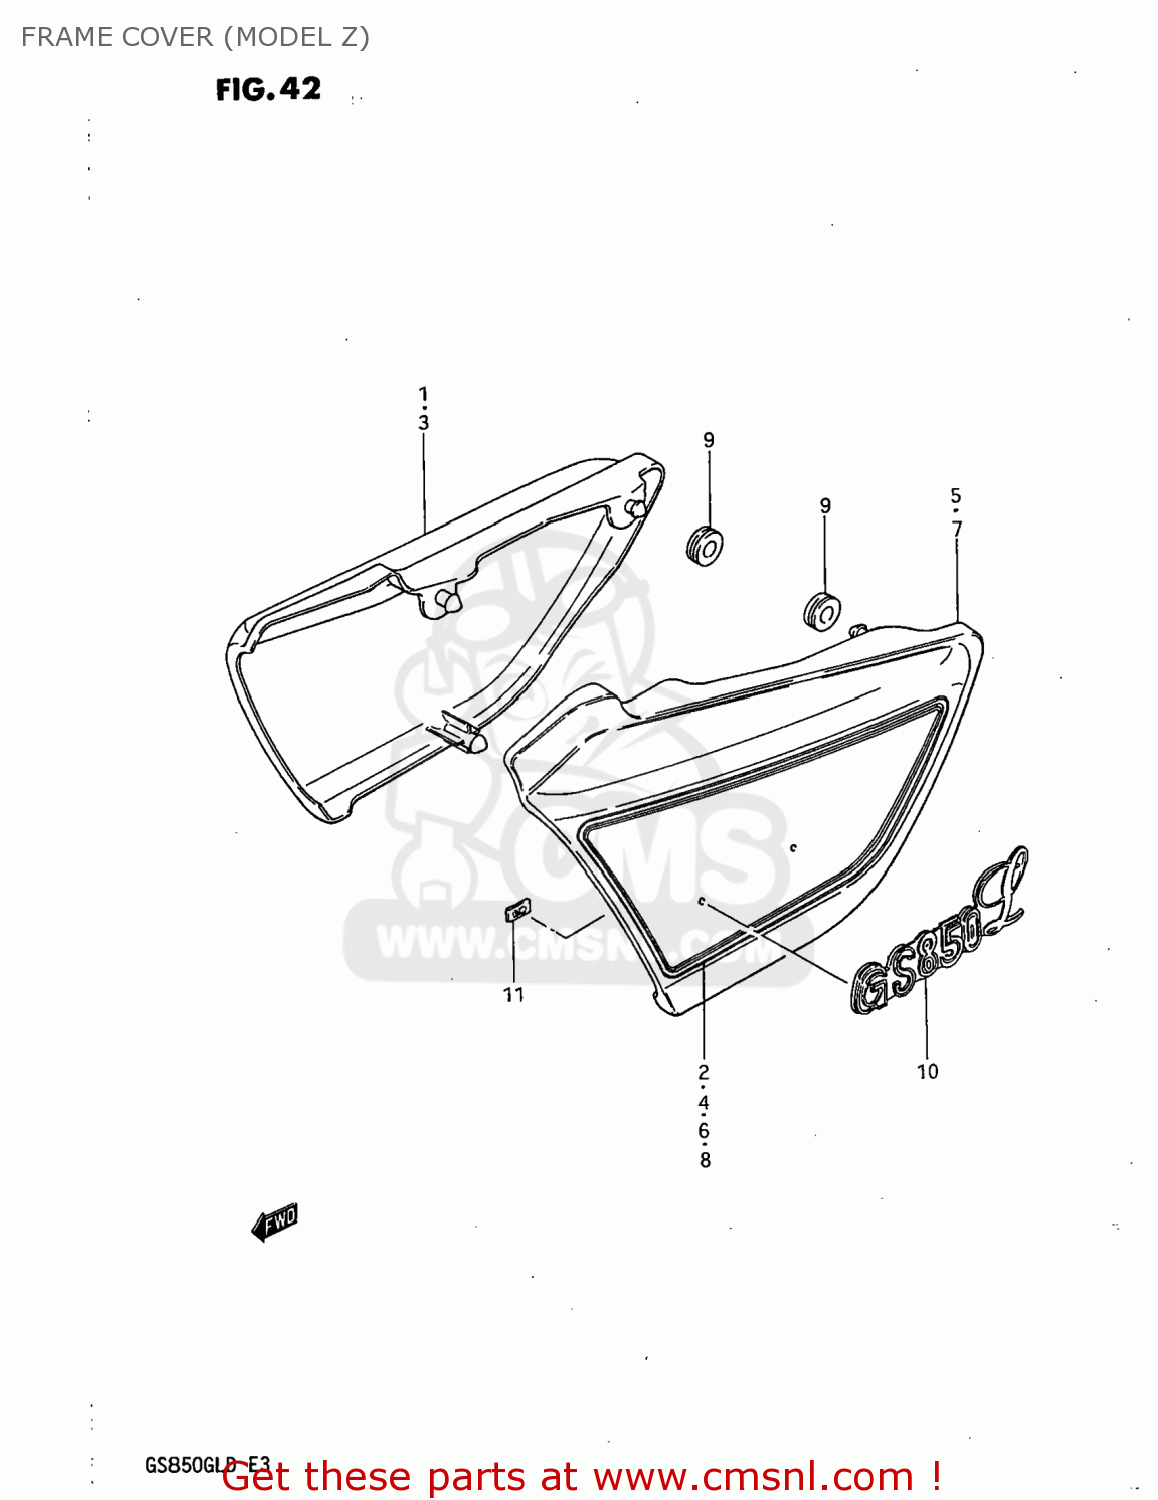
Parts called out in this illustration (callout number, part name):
1	COVER,FRAME,RIGHT
2	TAPE,FRAME COVER,RIGHT
3	COVER ASSEMBLY,FRAME,RIGHT
4	TAPE,FRAME COVER,RIGHT
5	COVER,FRAME,LEFT
6	TAPE,FRAME COVER
7	COVER ASSEMBLY,FRAME,LEFT
8	TAPE,FRAME COVER
9	CUSHION
10	EMBLEM
11	NUT
